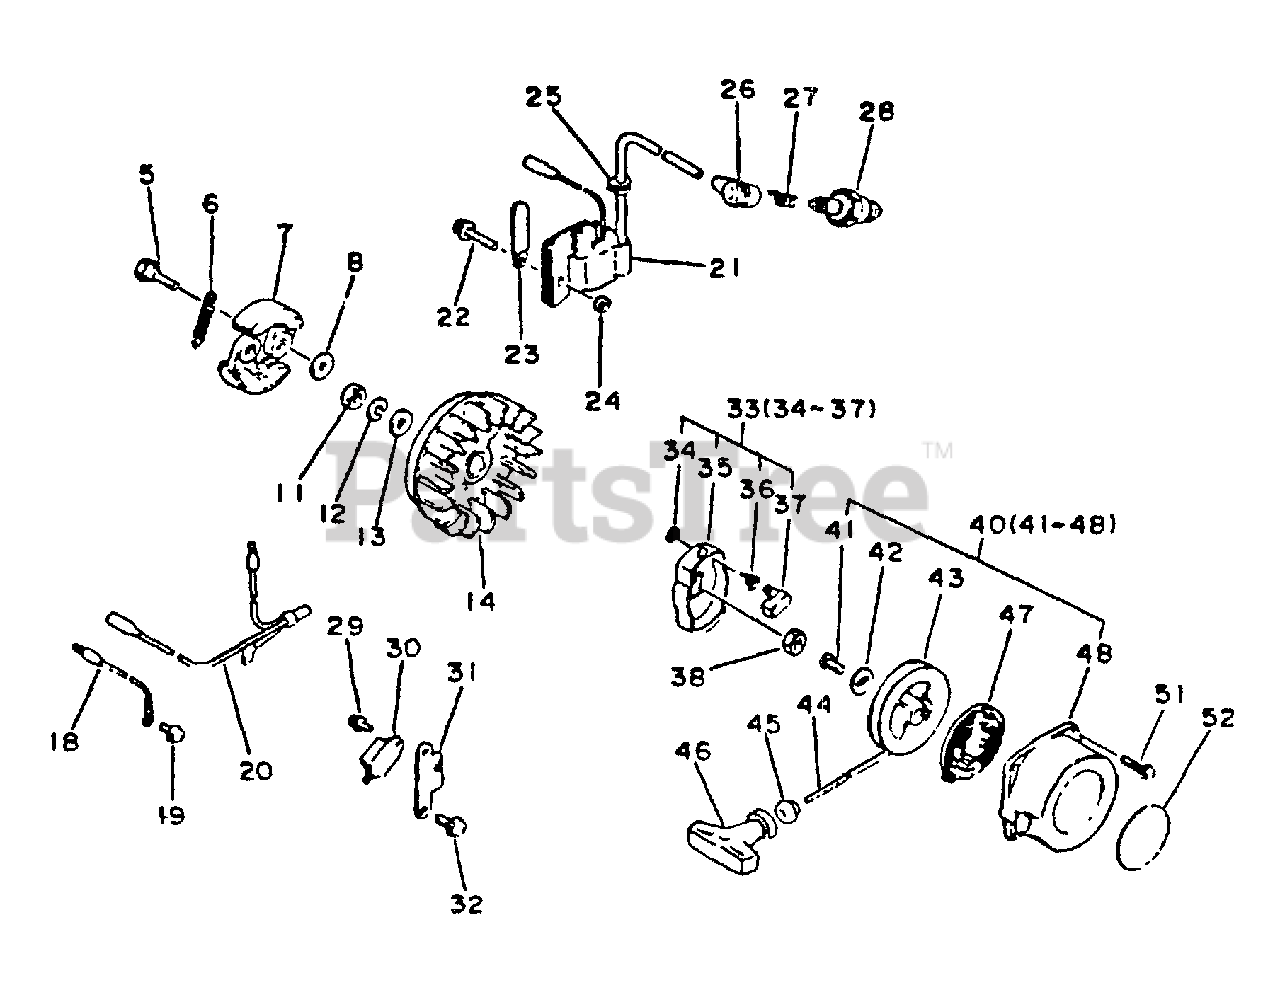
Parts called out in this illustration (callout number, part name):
5	BOLT, CLUTCH
6	SPRING, CLUTCH
7	SHOE, CLUTCH
8	WASHER - 6
12	LOCKWASHER - 8
14	FLYWHEEL
18	LEAD - GROUND
19	SCREW - 5X10
21	COIL, IGNITION
22	SCREW - 5X25
24	SPACER
26	CAP, SPARK PLUG
27	TERMINAL, SPARK PLUG CAP
28	SPARK PLUG -- CJ-7Y
29	SCREW - 4X8
30	COIL, IGNITION
31	BRACKET, IGNITION COIL
32	SCREW - 5X12
33	STARTER PAWL ASSY
34	RING, RETAINING - 4
35	CATCHER, PAWL
36	SPRING, RETURN
37	PAWL, STARTER
40	STARTER ASSY
43	REEL, ROPE
44	ROPE, STARTER - 4X880
45	GUIDE, ROPE
46	GRIP, STARTER
47	SPRING, REWIND
48	CASE, STARTER - ORANGE
51	SCREW - 4X20
52	LABEL - ECHO
